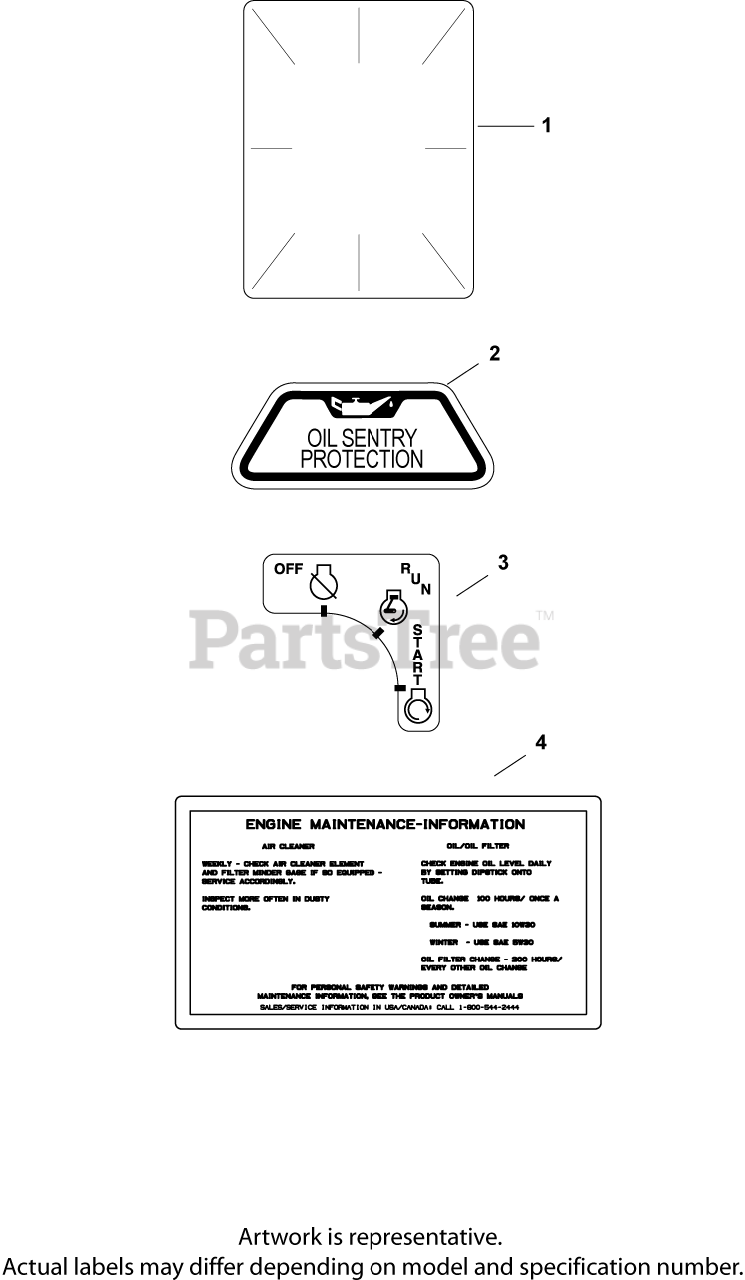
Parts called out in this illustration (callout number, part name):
1	DECAL, CLEAR LAMINATE USE 25 113 70-S
2	DECAL, OIL SENTRY - (#DSC)
3	DECAL, KEY SWITCH
4	DECAL, AIR CLEANER - (#DSC)
